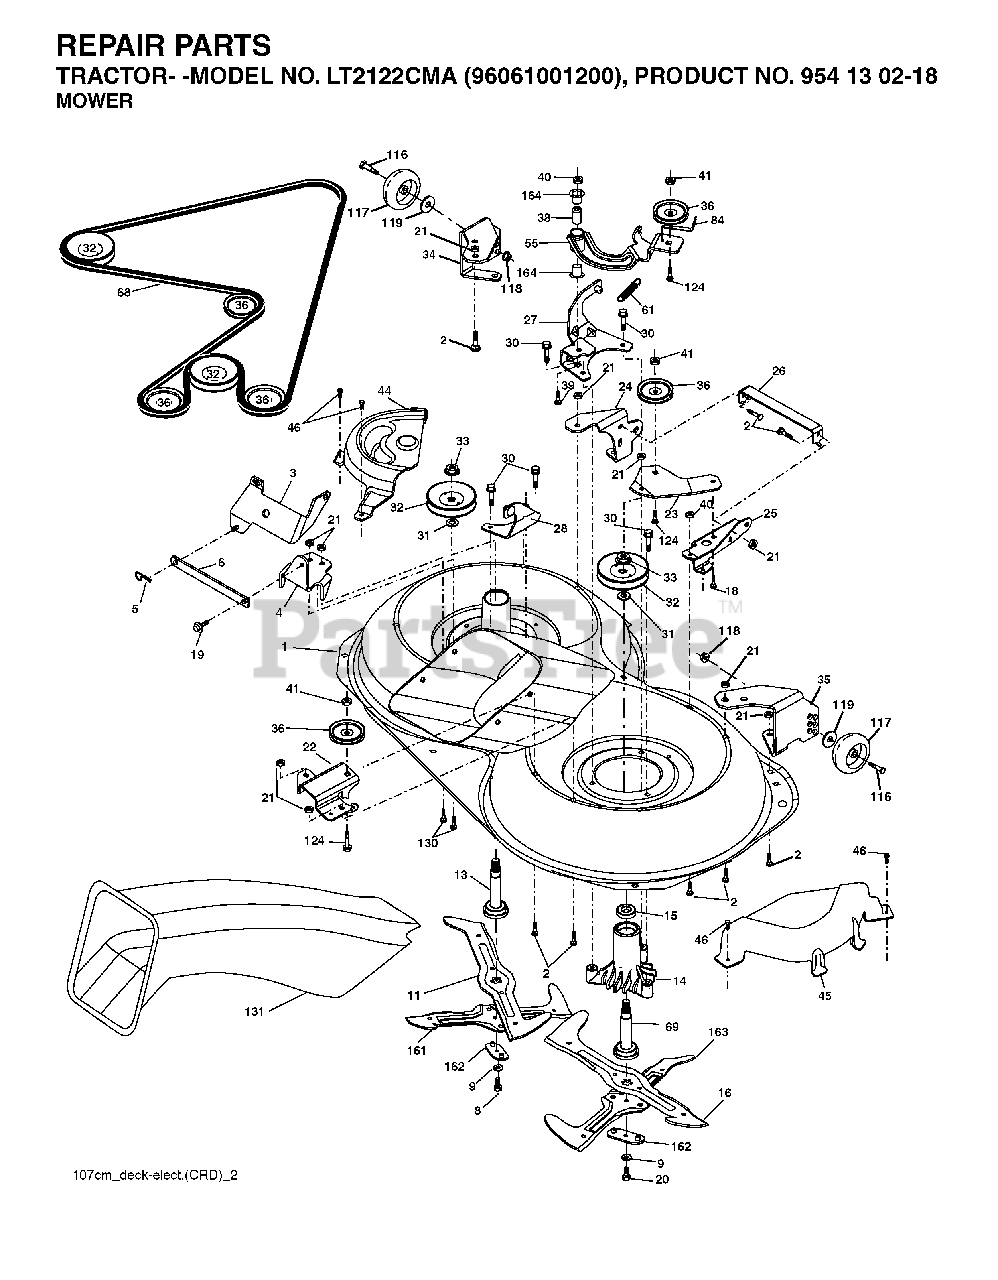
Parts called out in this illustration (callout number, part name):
2	BOLT
3	BRACKET
5	RETAINER-SPRNG RB
6	BAR SWAY
9	LOCKWASHER
11	BLADE.3N1.LH.CRD
13	SHAFT ASM VENT
14	HSG MANDREL
16	BLADE.3N1.RH.CRD
19	BOLT SHD 5/16-18
21	LOCKNUT
22	BRACKET
23	BRACKET
26	BRACE
27	BRACKET
30	SCREW, WASHER HEAD
31	WASHER.SPACER.MANDREL
33	NUT, FLG TOPLOCK 9/16"
36	PULLEY.IDLER.4.25
40	LOCKNUT
41	NUT LOCK FLG 3/8-16 UNC
45	MANDREL COVER
46	SCREW.1/4-20X5/8
55	ARM IDLER
68	HEX-BELT 107 MOWER
69	SHAFT.ASM.W/LWR.BRG.RH.THREAD
84	KEEPER, BELT IDLER
116	SHOULDER BOLT
117	WHEEL GAGE DONUT
118	LOCKNUT
119	WASHER
124	BOLT.3/8-16X1.50
131	CHUTE BAGGER
164	BRNG T
